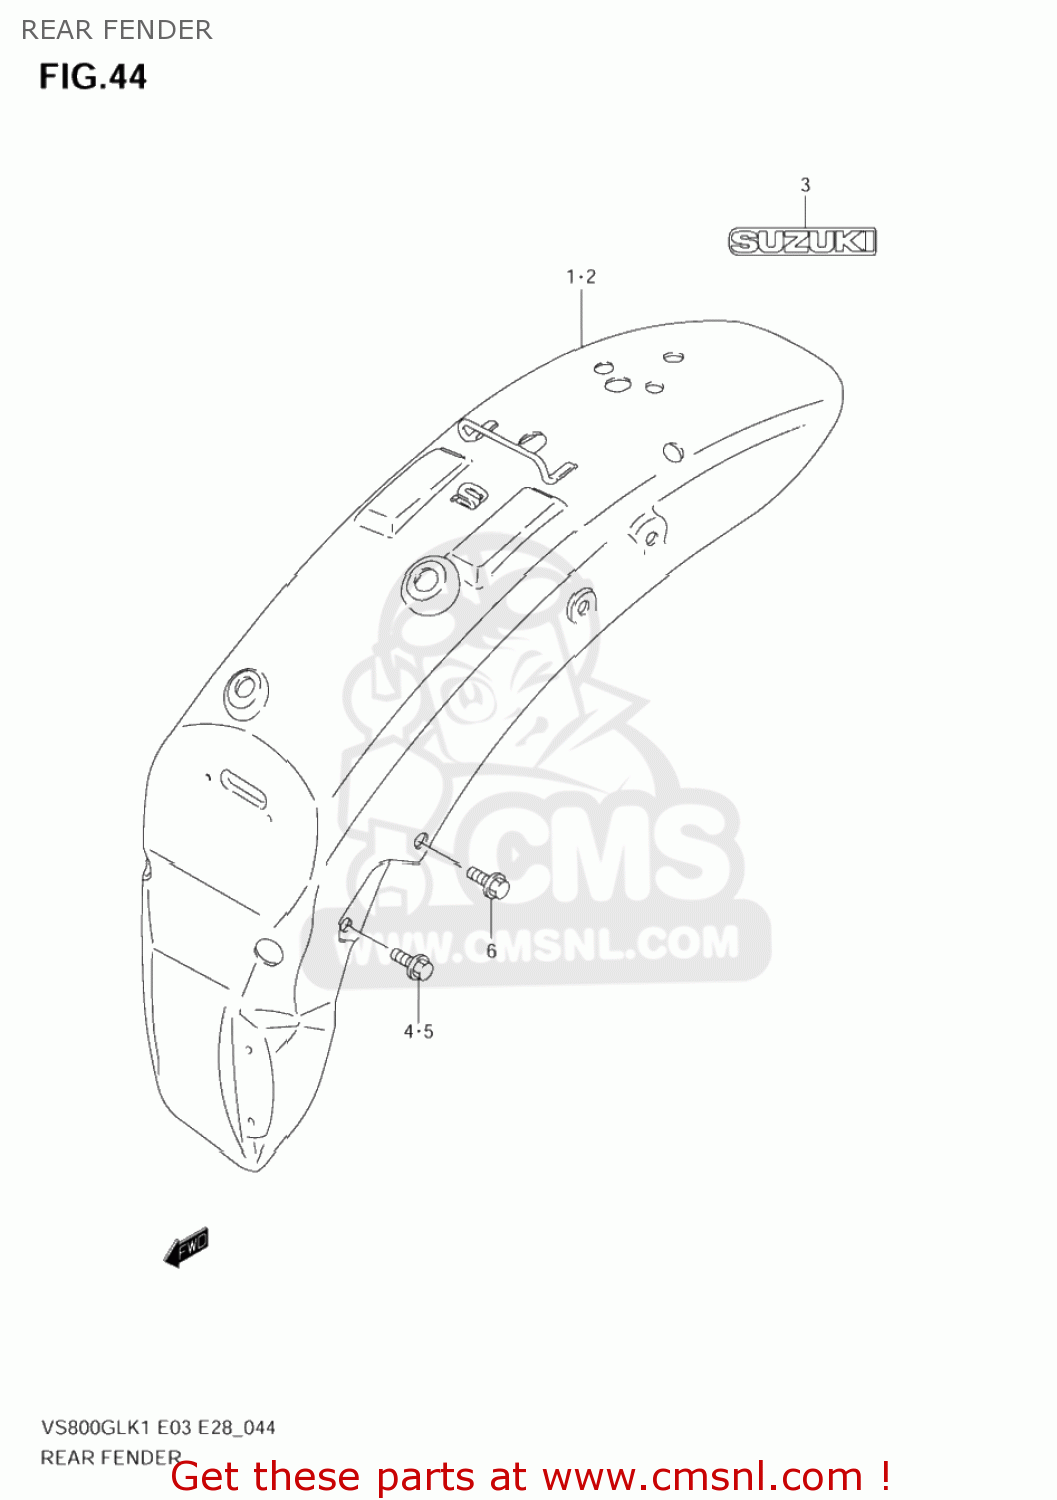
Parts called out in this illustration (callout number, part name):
1	FENDER,RR
2	FENDER ASSY,RR
3	EMBLEM,SUZUKI
4	BOLT
5	BOLT
6	BOLT
